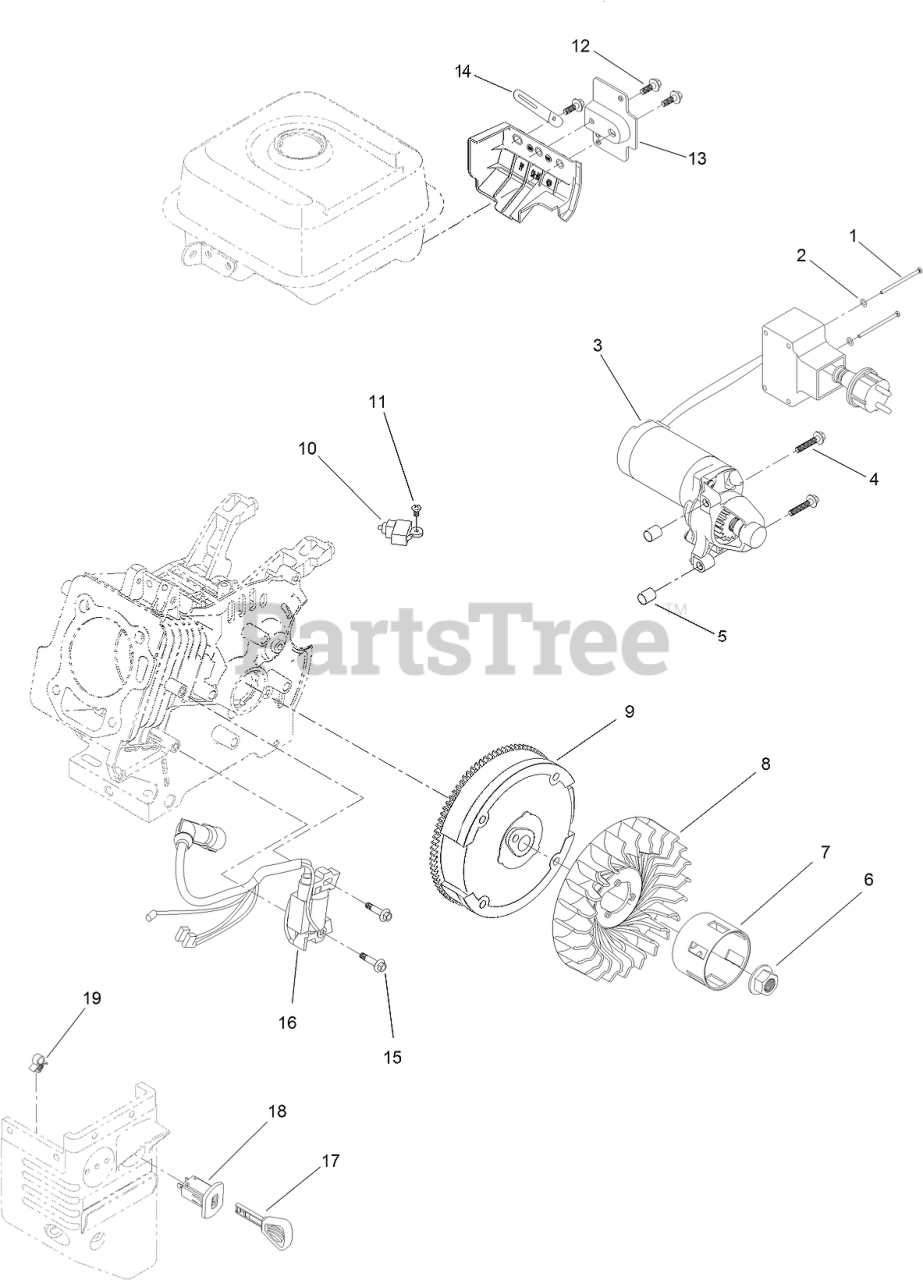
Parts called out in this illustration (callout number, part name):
1	SCREW-BHP
2	WASHER-PLAIN
3	MOTOR-STARTER
4	SCREW-FLANGE
5	PIN-DOWEL
6	NUT-FLANGE
7	CUP-STARTER
8	FAN-COOLING
9	FLYWHEEL AND RING GEAR ASM
10	SWITCH-KILL, ENGINE
11	SCREW-PPH
12	SCREW-HHF
13	BRACKET-SWITCHBOX, STARTER
14	CLIP-HARNESS, WIRE
15	SCREW-HHF
16	IGNITION COIL ASM
18	SWITCH-KEY
